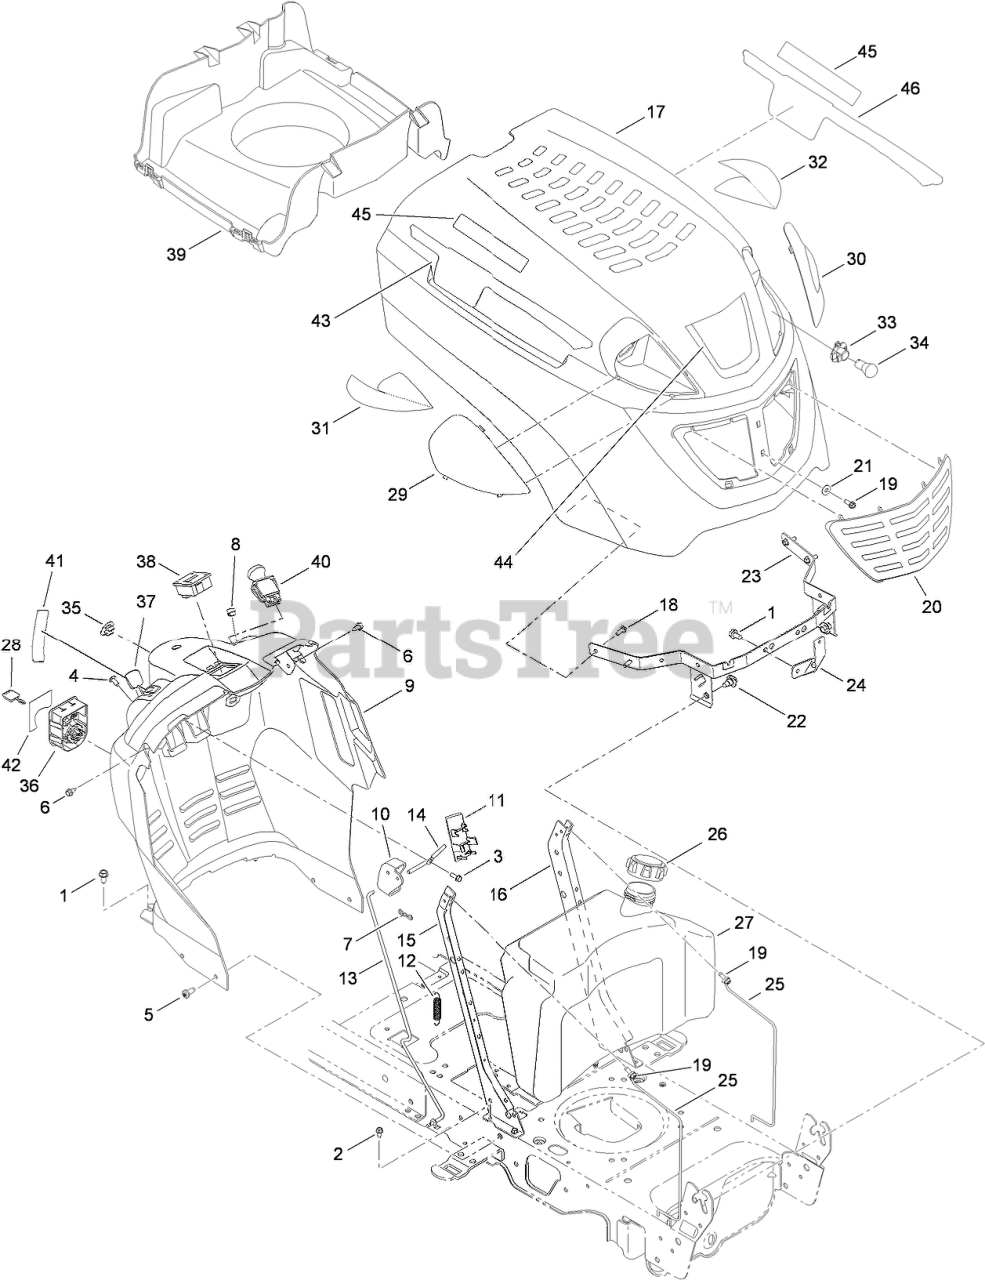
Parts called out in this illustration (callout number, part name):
1	SCREW-TAP
2	SCREW-HWHTF
3	SCREW-TAP
4	SCREW-TAP
5	SCREW-TAP
6	SCREW-HWH
7	PIN-COTTER
8	CAP-PLUG, HOLE
9	DASH-ELECTRIC, PTO
10	LEVER-DASH
11	COVER-CRUISE
12	SPRING-EXTENSION
13	ROD-LATCH
14	ROD-LEVER, BENT
15	SUPPORT-DASH, PLATE (RH)
16	SUPPORT-DASH, PLATE (LH)
19	SCREW-TAP
21	WASHER-FLAT
22	BOLT-SHOULDER, TAP
23	BRACKET-PIVOT
24	BRACKET-SUPPORT, HOOD
25	ROD-SUPPORT
26	CAP-FUEL
27	TANK-FUEL, 3 GAL
28	KEY-IGNITION
29	LENS-RH
30	LENS-LH
31	REFLECTOR-RH
32	REFLECTOR-LH
33	SOCKET-HEADLIGHT
34	LAMP-12V, MINIATURE
35	PLUG-CHOKE
36	MODULE-SWITCH, IGNITION
37	CABLE-THROTTLE
38	METER-HOUR
39	PLENUM-HOOD
40	SWITCH-ELECTRIC, PTO
41	DECAL-THROTTLE
42	DECAL-SWITCH, IGNITION
43	DECAL-HOOD, RIGHT SIDE
44	DECAL-HOOD
46	DECAL-HOOD, LEFT SIDE
